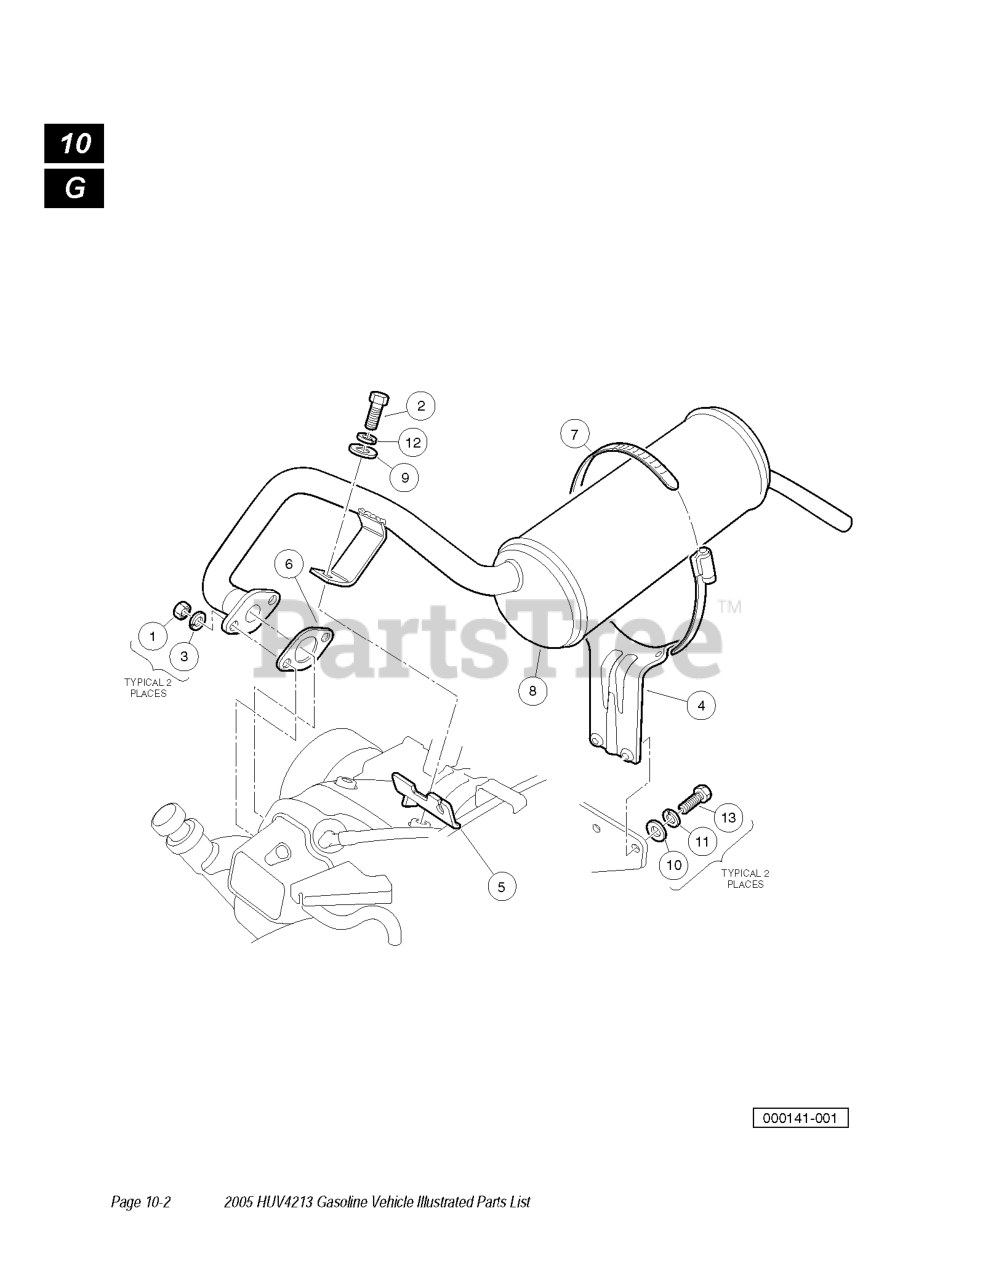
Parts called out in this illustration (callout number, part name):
1	NUT, M8-1.25 HEX
2	SCREW, M8-125 X 22 HEX GR.8.8
4	BRACKET, MUFFLER MOUNTING
5	BRACKET, GOVERNOR CABLE ENGINE
6	GASKET, FE350 EXHAUST
7	CLAMP, 5" MUFFLER HOSE
8	EXHAUST SYSTEM, FE400
9	WASHER, 5/16 TYPE A FLAT
10	WASHER 1/4 FLAT
11	LOCKWASHER, 1/4 HELICAL SPLIT
12	LOCKWASHER, 5/16 SPLIT
13	SCREW, 1/4-20 X .75 HEX
